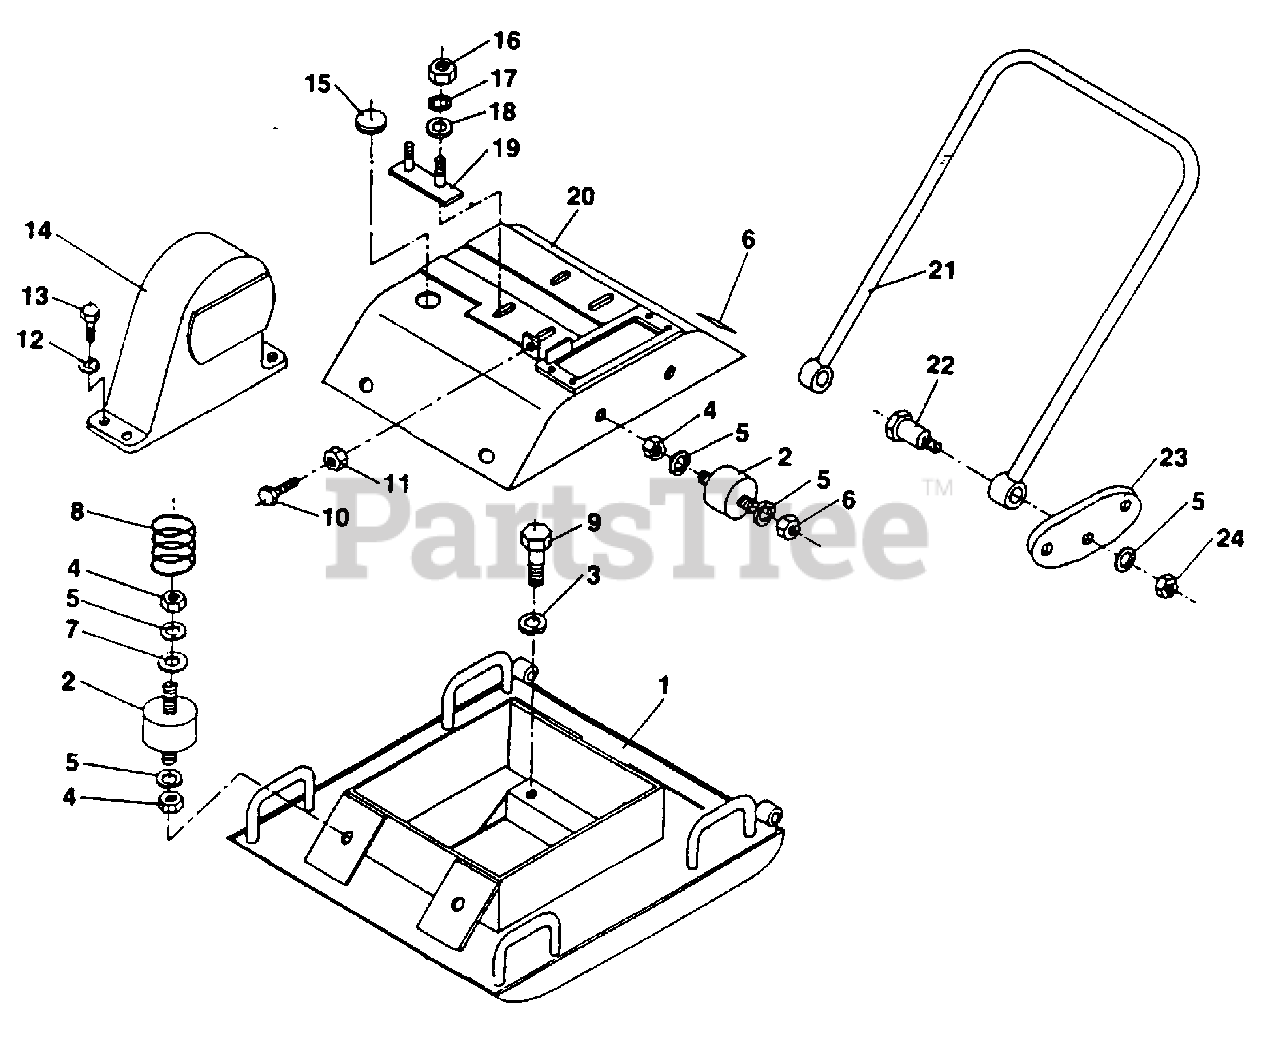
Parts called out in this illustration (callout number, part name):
1	PLATE- Vibration
2	ABSORBER- Shock (m8)
3	WASHER- Spring (m16)
4	NUT- Hex (m12)
5	WASHER- Spring (m12)
6	DECAL- Caution
7	WASHER- Plate (m12)
8	SPRING- Earth
9	BOLT- (m16 x 65)
10	BOLT- Hex (m1O x 45)
11	NUT- Hex (m1O)
12	WASHER- Spring (m1O)
13	BOLT- Hex (m10 x 25)
14	COVER- Belt
16	NUT- Hex (m8)
17	WASHER- Spring (m8)
18	WASHER- Plate (m8)
19	SEAT- Engine
20	COVER-Vibration Plate
22	PIN- Bracket
23	BRACKET- Handle
24	NUT- Hex (m12)
